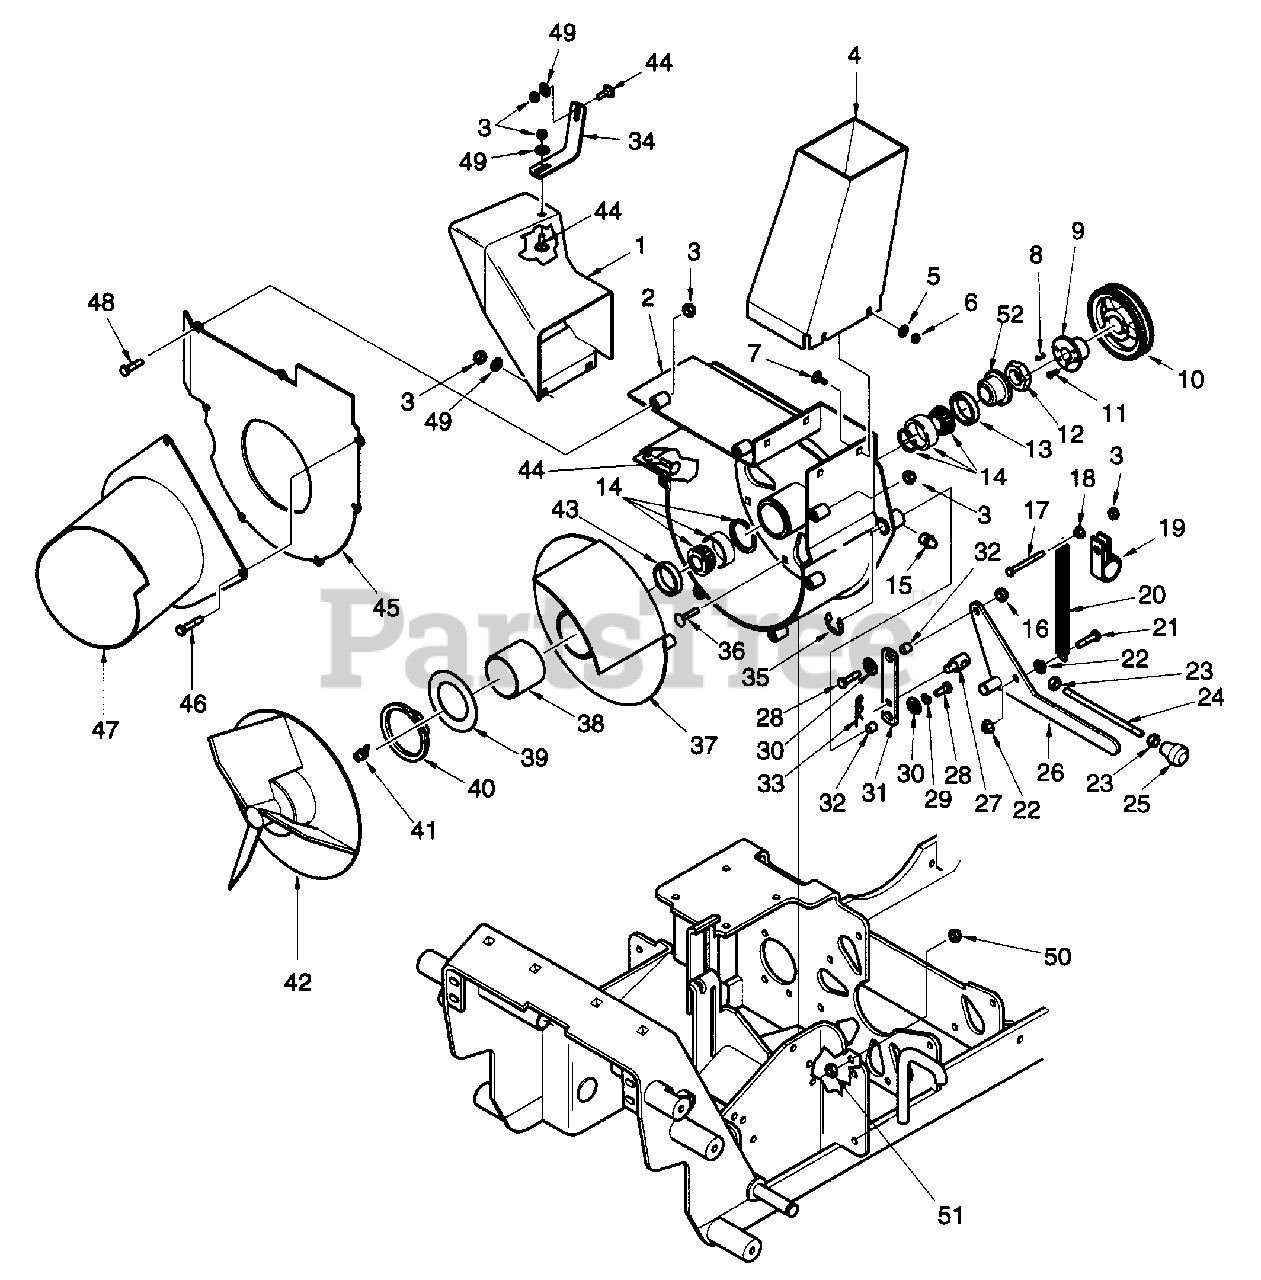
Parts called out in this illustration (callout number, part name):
1	CHUTE, SIDE DISCHARGE
2	HOUSING, BLOWER
3	HEX LOCKNUT, ELASTIC STOP, 5/16-18
4	OUTLET, BLOWER
5	FLATWASHER, 1/4(.281 X .625 X .065)
6	HEX LOCKNUT, ELASTIC STOP, 1/4-20
7	CARRIAGE BOLT, 1/4-20 X 3/4
8	KEY, 1/4 X 1/4 X 1-1/4
9	HUB, TAPERED, 1.00 BORE
10	PULLEY, 5.25 OD
11	BOLT, HEX HEAD, 1/4-20 X 1-3/8
12	NUT, 1-1/16-18 L.H.
13	SEAL, 2.00 OD X 1.50 BORE
14	ROLLER BEARING ASSEMBLY
15	GREASE FITTING
16	HEX LOCKNUT, 3/8-16
17	BOLT, HEX HEAD, 5/16-18 X 2-1/2
18	SERR. FL. HEX NUT, 5/16-18
20	SPRING
21	BOLT, HEX HEAD, 3/8-16 X 1-1/2
22	SERR. FL. HEX NUT, 3/8-16
23	HEX NUT, 3/8-16
24	STUD, 3/8-16 X 9.00
25	KNOB, SHIFTER
26	LEVER, BLOWER GATE
27	JOINT, SWIVEL
28	BOLT, HEX HEAD, 3/8-16 X 1.0
29	LOCKWASHER, 3/8
30	FLATWASHER, 3/8(.406 X .812 X .065)
31	LINK, BLOWER GATE
32	SLEEVE
33	HAIRPIN, COTTER, .080 X 1.19
34	MOUNTING BRACKET, DISCHARGE CHUTE
35	RETAINING RING, .625 "E"
36	CARRIAGE BOLT, 3/8-16 X 1-1/4
37	GATE
38	BUSHING, OILITE, 2.505 ID
39	WASHER, GATE RETAINER
40	RETAINING RING, 2.50 EXT
41	GREASE FITTING, 65DEG
42	FAN, BLOWER
43	SEAL, 2.00 OD X 1.625 BORE
44	CARRIAGE BOLT, 5/16-18 X 3/4
45	FRONT, BLOWER HOUSING
46	BOLT, HEX HEAD, 5/16-18 X 1-1/2
47	ADAPTER, BLOWER INLET
48	BOLT, HEX HEAD, 5/16-18 X 1-1/2
49	FLATWASHER, 5/16(.375 X .875 X .083)
50	HEX LOCKNUT, ELASTIC STOP, 3/8-16
51	NUT, JAM, 3/8-16
52	BUSHING
